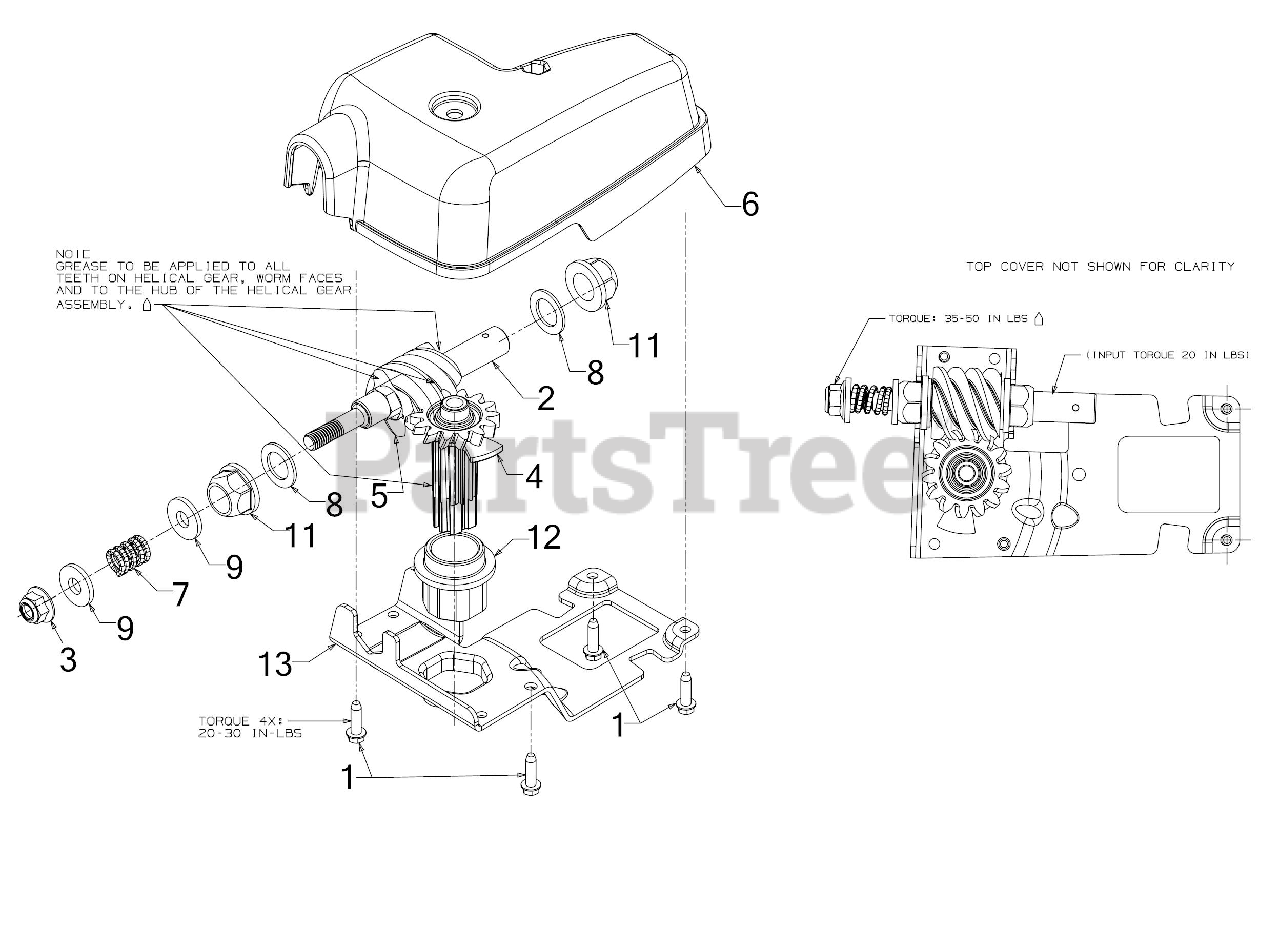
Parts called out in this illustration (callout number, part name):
1	SCREW #12-16 .75
2	WORM DRIVE SHAFT .625
4	HELICAL GEAR-14T
5	WORM GEAR
6	CHUTE GEARBOX COVER
7	COMPRESSION SPRING
8	FLAT WASHER
9	WASHER
11	FLANGE BEARING
12	HEX FLANGE BEARING
13	CHUTE ROTATION BRACKET
